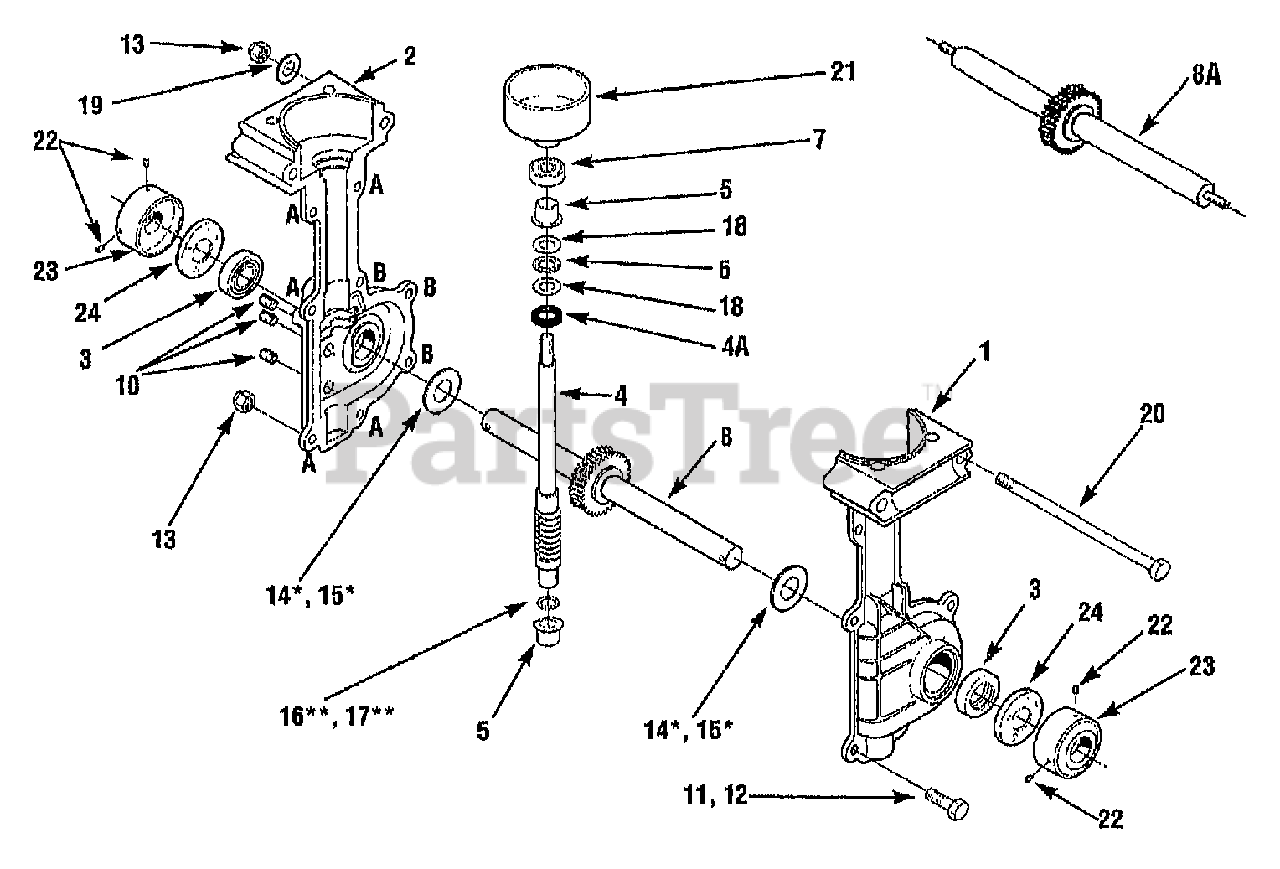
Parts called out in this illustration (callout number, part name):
1	ASSM-TRANS CASE LEFT W/PRESSED IN BUSHING
2	ASSM-TRANS CASE RIGHT W/PRESSED IN BUSHING
3	SEAL-PINION SHAFT PT/85030/00
4	SHAFT-WORM PT/85032/00
4A	SEAL-OIL INPUT SHAFT
5	BEARING-INPUT
6	BEARING-THRUST PT/85034/00
7	BEARING-BALL PT/85035/00
8A	ASSM-OUTPUT SHAFT {120970300100 AND BELOW}
10	PLUG-PIPE 1/8 NPT
11	SCR-HH 1/4-20 X .875
12	SCR-HH 1/4-20X1.0
13	NUT-LK 1/4-20
14	WASHER-THRUST .775X.05 AS REQ'D
15	WASHER-THRUST .775X.05 AS REQ'D
16	WASHER-THRUST .505X.02 AS REQ'D
17	WASHER-.76X.5X.04 THRUST AS REQ'D
18	WASHER-THRUST .92X.5X.06
19	WASHER-FLAT 1/4 SAE
20	SCR-HH 1/4-20X5
21	ASSM-CLUTCH & DRUM
22	SCR-SET 1/4-28X.38 HXSKT
24	WASHER-FELT 1.5X.72X.13
